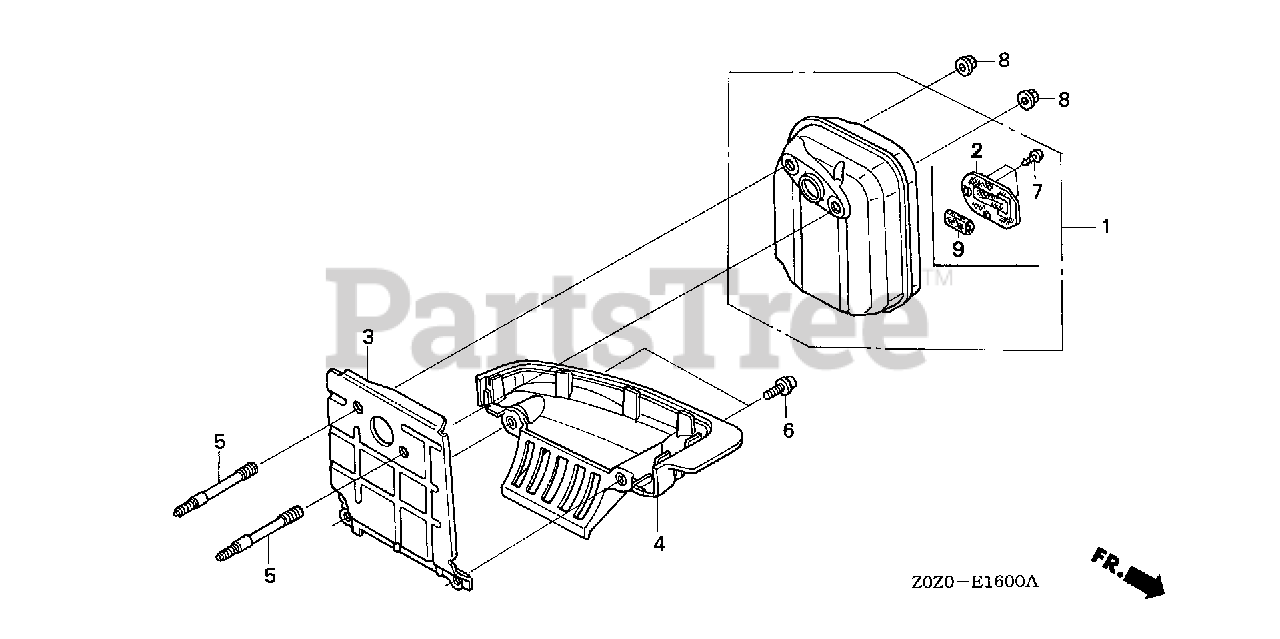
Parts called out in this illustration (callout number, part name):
1	MUFFLER (ARRESTER)
2	ARRESTER, SPARK
3	GUIDE, AIR
4	GUIDE, AIR (LOWER)
5	BOLT, STUD (5X56.5)
6	BOLT, SOCKET (5X16)
7	SCREW, TAPPING (4X6)
8	NUT, SELF-LOCK (5MM)
9	FILTER, EX.
